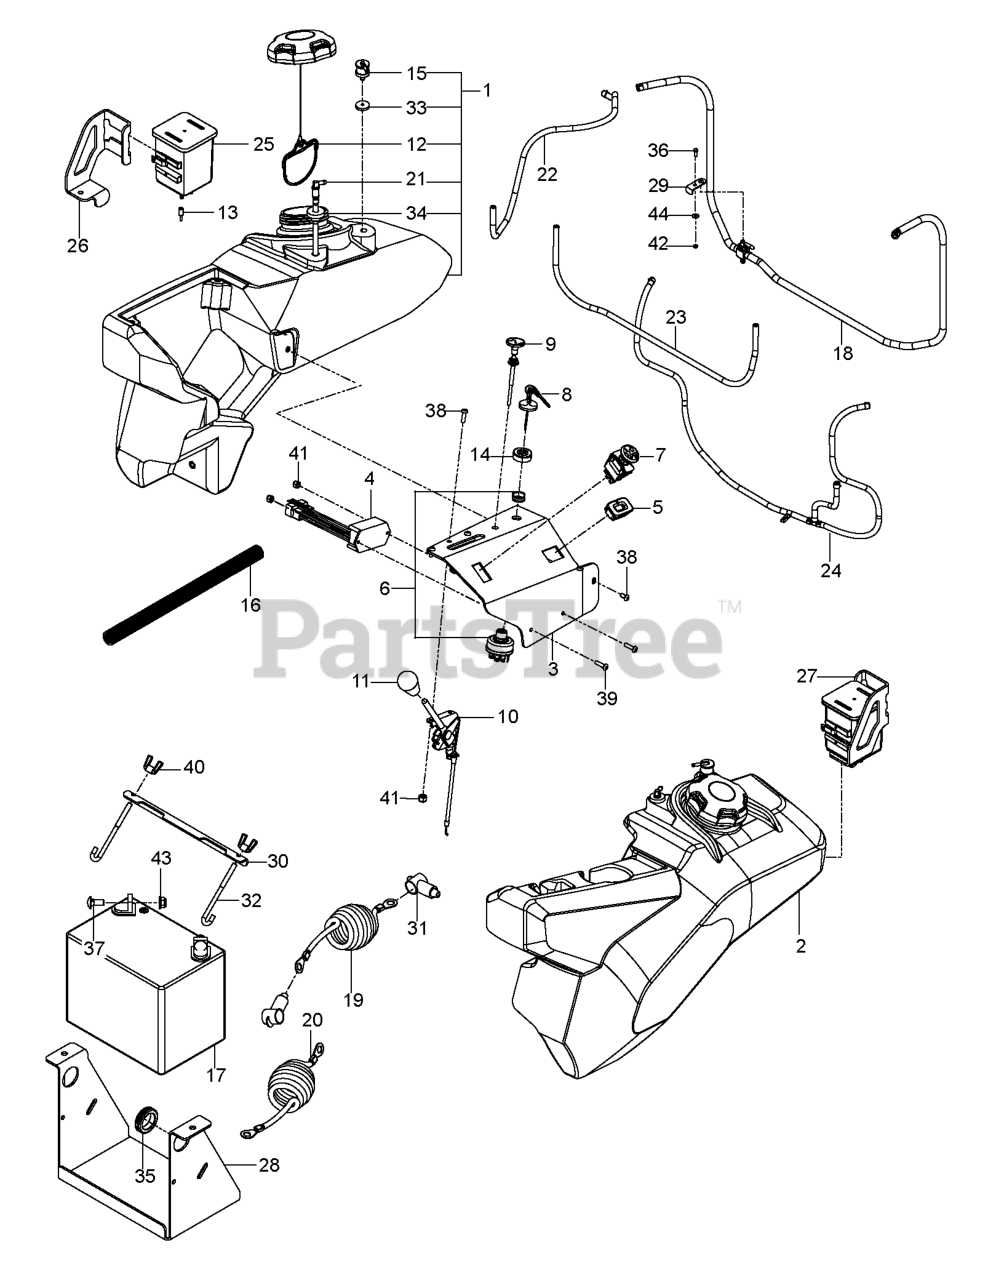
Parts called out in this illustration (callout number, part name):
1	FUEL TANK ASM RH GRAY PZ
2	FUEL TANK LH PZ GRAY
3	PANEL.CONTROL.GAS.GRAY
4	TIMER, SEAT
5	GUAGE.SRVCMNDR.HRMTR.
6	SWITCH, IGNITION, INDAK
7	RP SWITCH.PTO.TERMINAL.STD.RED
8	KEY, IGNITION
9	CABLE, CHOKE, 48"
10	CABLE, THROTTLE, 60"
11	KNOB - SHIFT
12	CAP, FUEL
13	CAP, VINYL
14	CAP IGNITION NUT
15	VALVE.FUEL.CHECK
16	LOOM, SPLIT, CONVOLUTED
17	BATTERY, 12 V 330 AMP
18	ASSEMBLY, FUEL LINE
19	CABLE, POSITIVE, 55"
20	CABLE, NEG, 55"
21	FITTING, FUEL
22	HOSE.3/16".VAPOR.LINE.33"LGTH
23	HOSE.3/16".VAPOR.LINE.30"LGTH
24	HOSE.ASM.VAPOR.LINE.21-30-39
25	CANNISTER, CARBON
26	MOUNT, CANISATER, RT
27	MOUNT, CANISTER, LT
28	BRACKET, BATTERY, BLK
29	BRACKET,FUEL VALVE, BLACK
30	BRACKET.BATTERY.MOUNT.PLATED
32	HOOK, "J"
33	GROMMET, CHECK VALVE
34	RUBBER GROMMET
35	RUBBER GROMMET
36	HCS 1/4C X 3/4 HCS
37	RP BOLT 5/16-18 X3/4 ZN/YEL GR
38	SCR #10-24 X 3/8 SKT HD BLK OX
39	SCR #10-24 X .75 SKT HD BLK
40	WING NUT 1/4
41	NUT 10-24 NYLOC
42	JAM NUT 1/4C (2 2 PW01)
43	5/16-18 NYLOC FLANGE NUT
44	WASHER 1/4 FLAT
